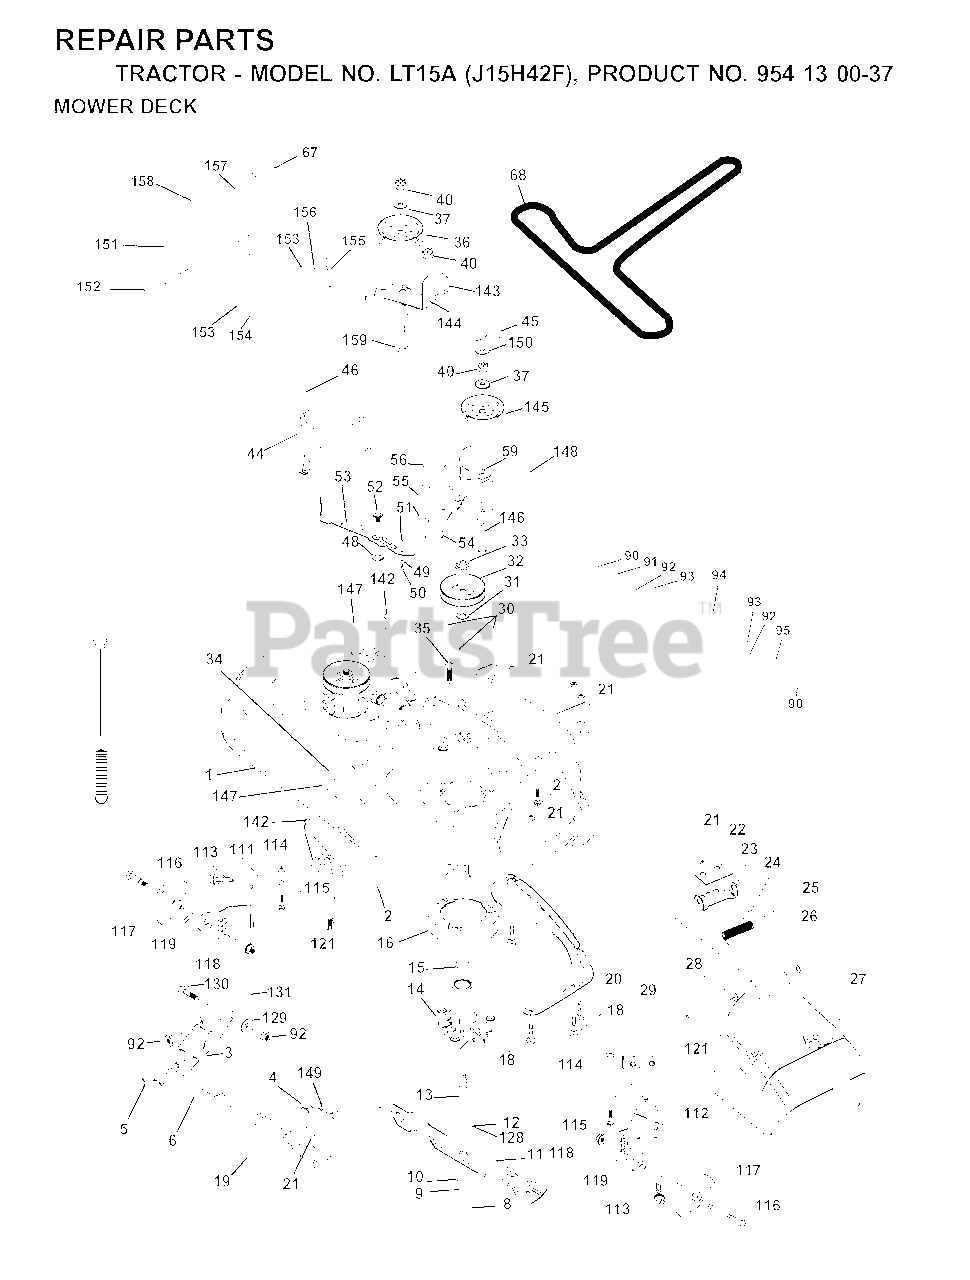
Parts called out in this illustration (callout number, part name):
1	42" DECK KIT
2	BOLT
3	BRKT ASM SWAY BAR
4	BRACKET SWAY BAR 42" DECK
5	RETAINER-SPRNG RB
6	REAR SUSP ARM
8	BLADE BOLT
9	LOCKWASHER
10	WASHER.BLADE
12	BEARING
13	SHAFT ASM VENT
14	HSG MANDREL
16	STRIPPER
17	BOLT
18	BOLT
19	BOLT SHD 5/16-18
20	BAFFLE.VORTEX
21	LOCKNUT
22	STIFFENER BRACKET
23	DEFLECTOR BRACKET
24	CAP-SLEEVE LT
25	SPRING TORSION
26	NUT PUSH M
27	SHIELD DEFLECTOR
28	WASHER
29	ROD.HINGE
30	SCREW THDROL ROLLING WASHER HD
31	WASHER
32	PULLEY/MANDREL
33	NUT
34	BOLT
35	FASTENER.XMAS.TREE
36	FLAT IDLER PULLEY
40	LOCKNUT
44	GUARD MANDREL LH BLACK
45	RETAINER M
46	SCREW.1/4-20X5/8
49	ROLLER ASSY
50	BOLT
53	ARM
54	HARDENED WASHER
55	ARM IDLER 42" MOWER LT/YT
56	SPACER.RETAINER.MOWER
59	GUARD, BELT
67	KNOB T (3/8 HOLE)
90	BOLT
91	BRACKET LH (A)
92	NUT
94	NOSE ROLLER
95	BRACKET RH (B)
111	BRACKET WHEEL GAUGE LH 42" DK
112	BRACKET WHEEL GAUGE RH 42" DK
113	SCREW 5/16"
114	NUT
115	BOLT
117	WHEEL.GAUGE.STANDARD
118	LOCKNUT
119	WASHER
121	BRACKET.EXTRD.GWL
128	WASHER FELT
129	WASHER
131	BOLT D
142	ARM SPRING BRAKE MOWER
143	BRACKET, ARM IDLER
144	KEEPER.BELT.42".CLUTCH.CABLE
145	PULLEY
146	BOLT, CARRIAGE IDLER
147	SPRING EXTENSION
148	IDLER RETURN SPRING
149	SPRING.RETAINER.YELLOW.ZINC
150	WASHER PM
151	BRACKET, CLUTCH CABLE
152	CLUTCH CABLE 42"
153	WASHER FLAT 3/8"
154	SPRING RETAINER
155	SPRING RETENTION LEVER
156	SPACER CLUTCH CABLE
157	ROD CLUTCH CABLE 3/8"
158	SCREW LT
159	BOLT
